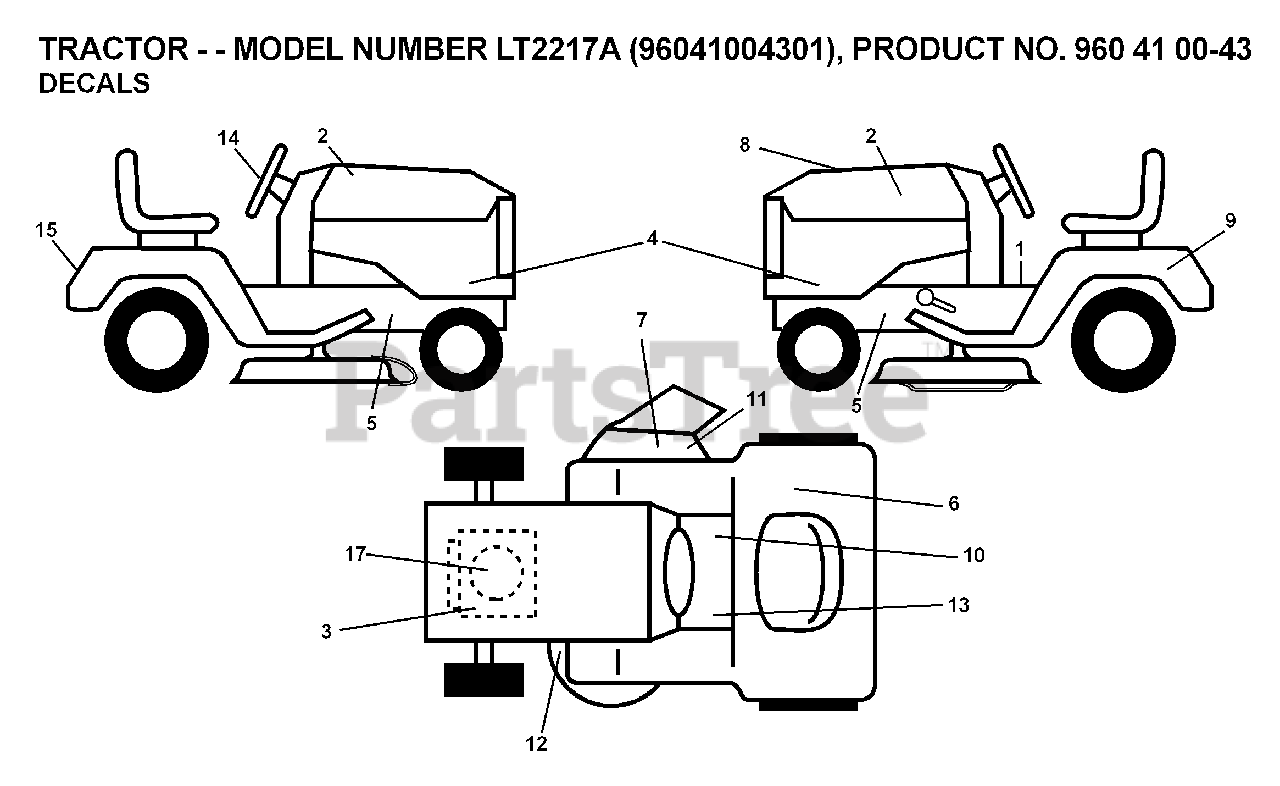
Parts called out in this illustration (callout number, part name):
7	DECAL.INTERNATIONL.CUTFINGER
9	DECAL BTRY SYMBOLS
10	DECAL PARK BRAKE
11	DECAL, DEFLECT WARNING
12	DECAL V BELT SCHEMATIC
